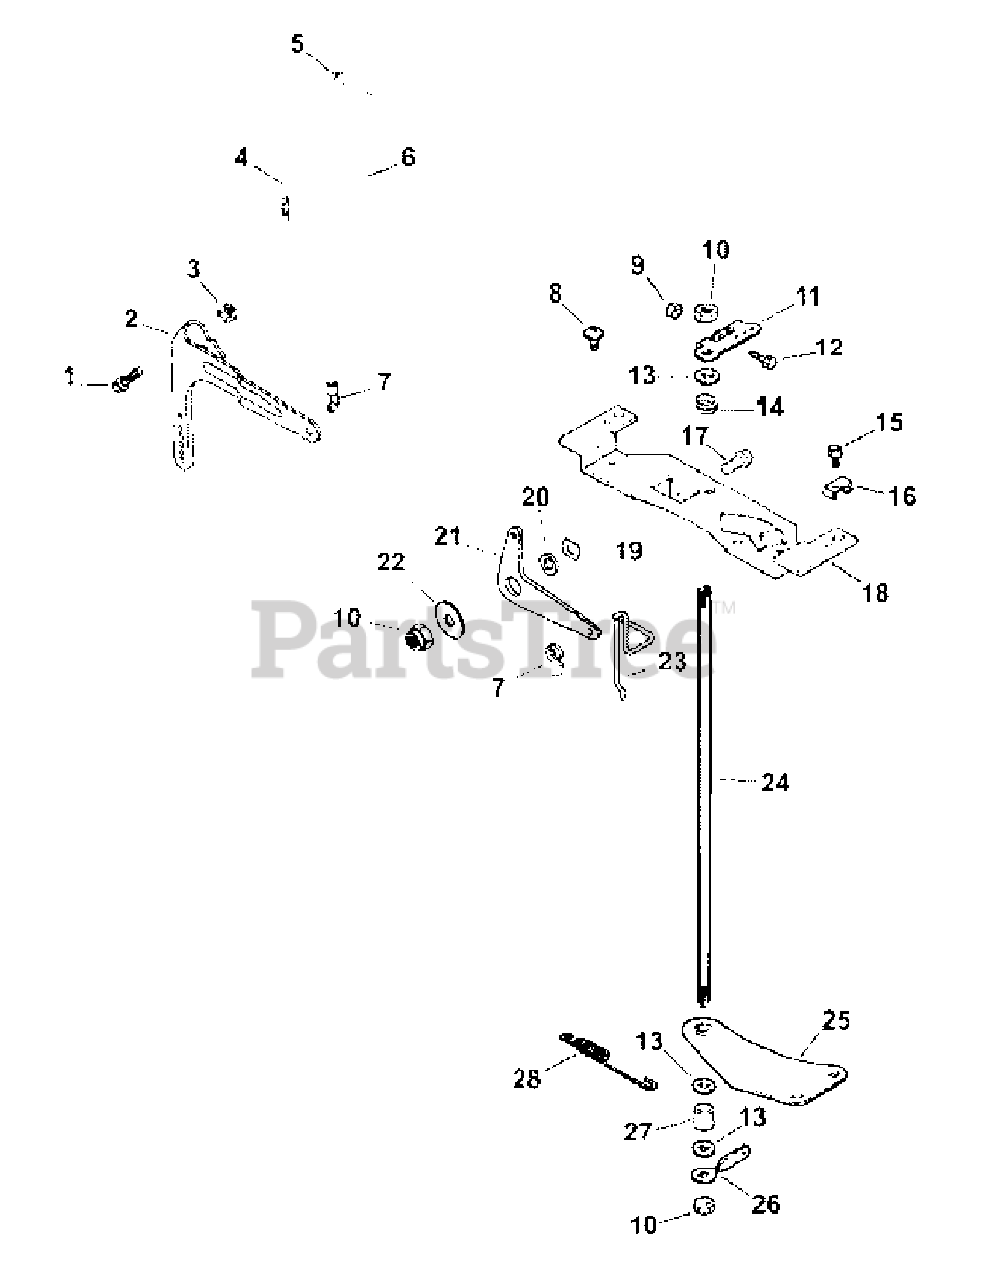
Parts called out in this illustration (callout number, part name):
2	Governor Lever
3	Hex Flange Nut
4	Linkage Spring
5	Linkage Retaining Bushing
6	Throttle Linkage
7	Throttle Linkage Bushing
8	Phillips Screw
10	Hex Lock Nut
11	Throttle Control Lever
12	Hex Cap Screw
13	Plain Washer
14	Throttle Shaft Spring
15	Hex Flange Screw
16	Cable Clamp
17	Hex Flange Screw
18	Control Bracket
20	Choke Lever
21	Plain Washer
22	Spring Washer
23	Choke Linkage
24	Throttle Shaft
25	Throttle Shaft Bracket
26	Throttle Control Lever
28	Governor Spring
